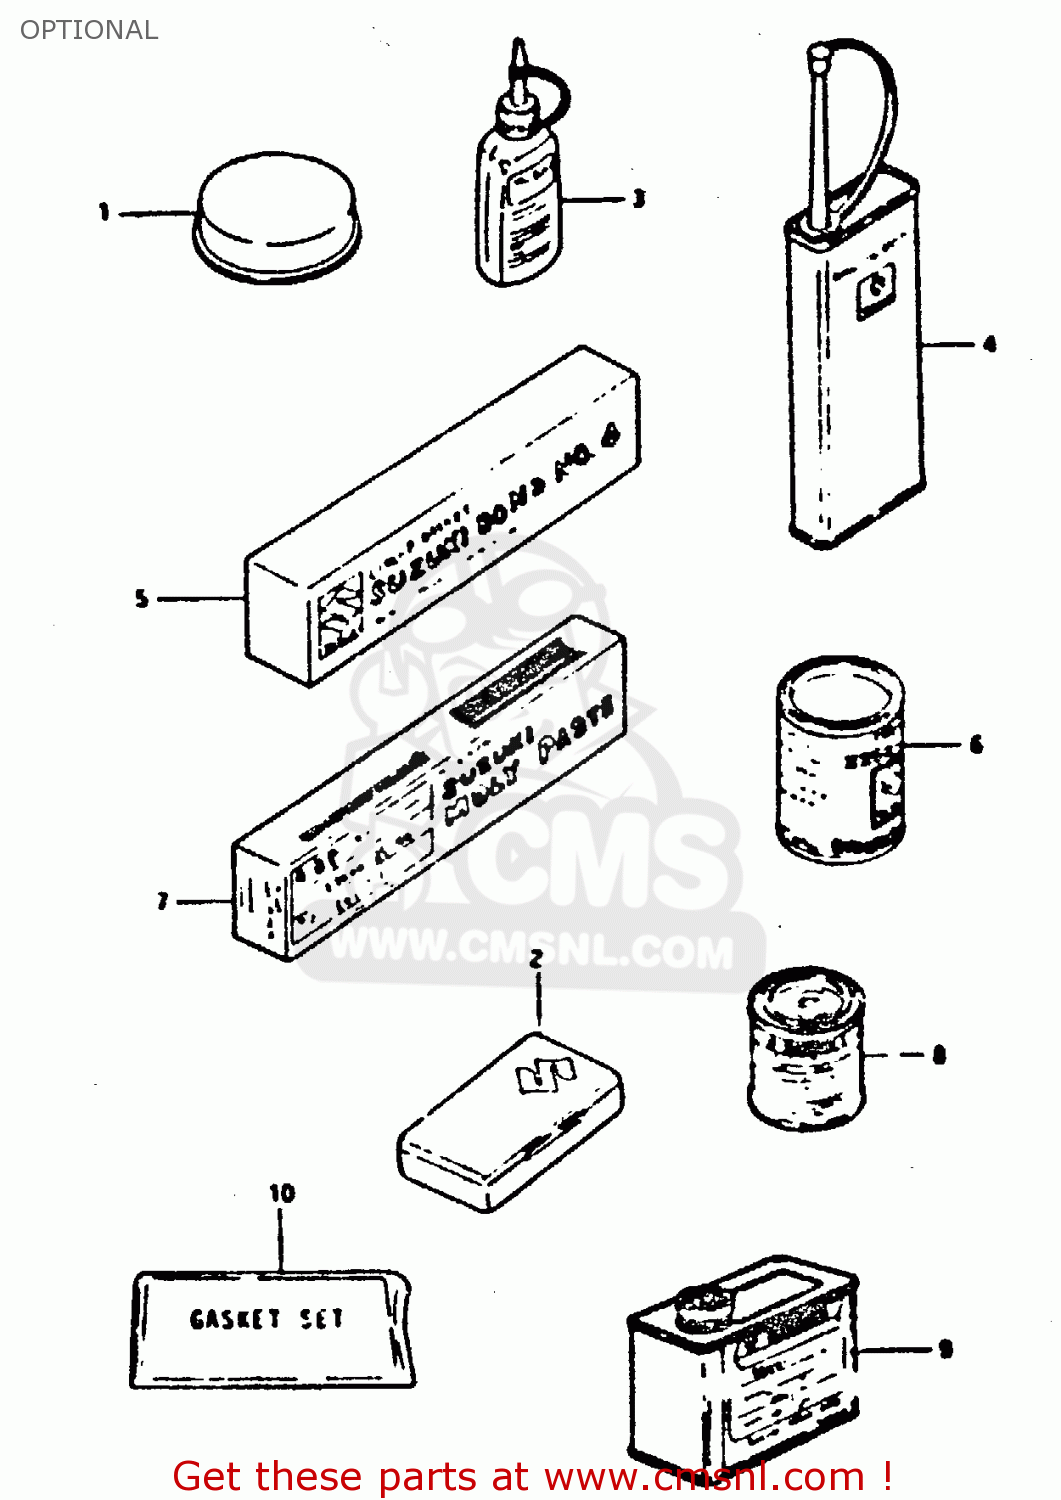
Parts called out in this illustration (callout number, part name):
1	GREASE,PBC FOR BRK PAD 20G
2	TUBE REPARING TOOL
3	THREAD LOCK NO.1342
4	THREAD LOCK NO.1401 CLEAR 200G
5	BOND 1104
6	GREASE(C)EP2 LITHIUM 150G
7	SUZUKI MOLY PASTE
8	PAINT,BLACK
9	PAINT (BLACK)
10	GASKET SET
